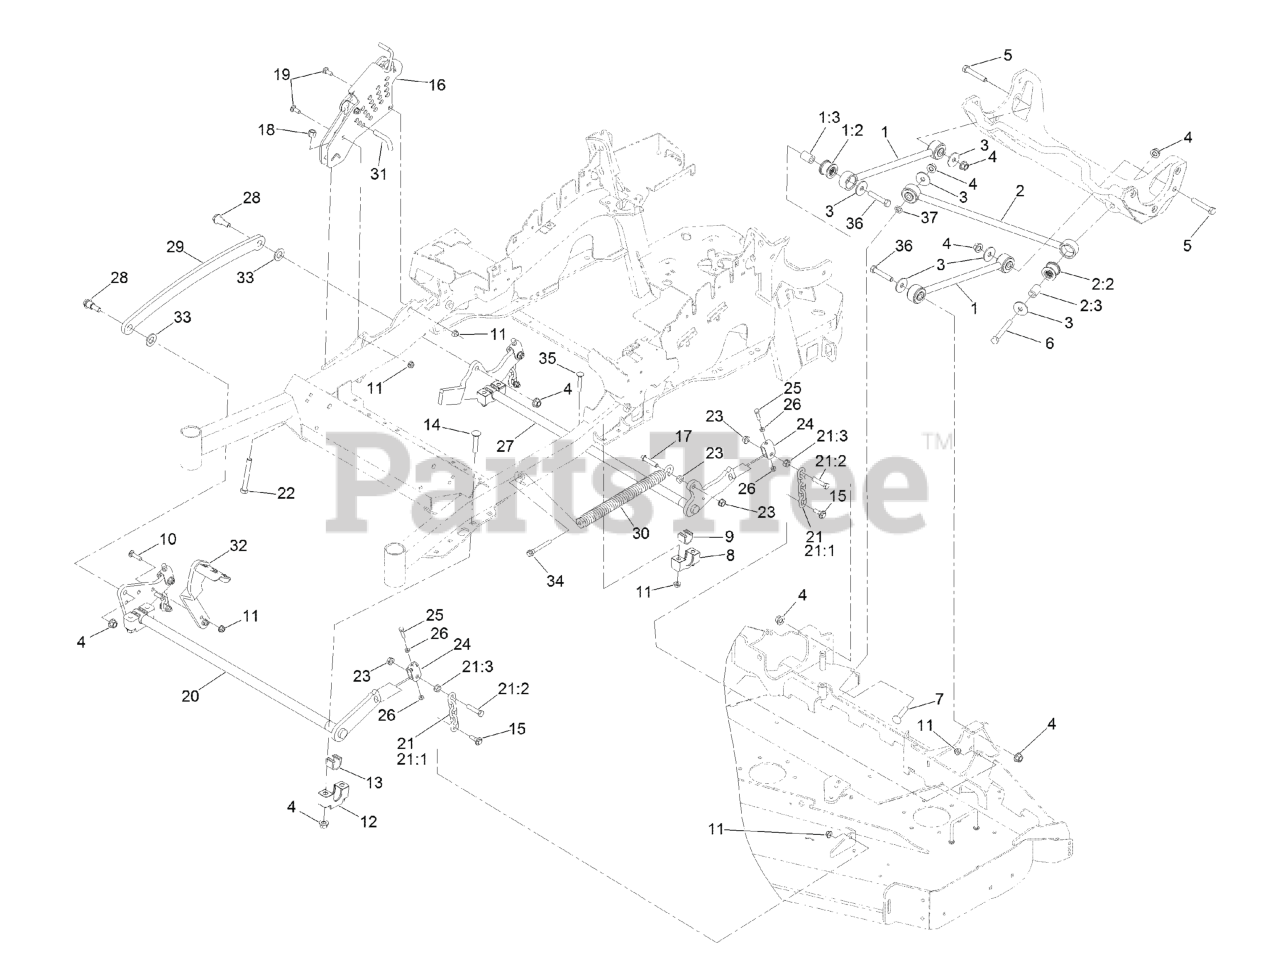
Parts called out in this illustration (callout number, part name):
1	DECK STRUT ASM
1:2	BUSHING-SUSPENSION, RUBBER
2	PANHARD ROD ASM
2:2	BUSHING-SUSPENSION, RUBBER
3	WASHER-THRUST
4	Nut-Lock 1/2-13
5	SCREW-HH
6	SCREW-HH
7	SCREW-CARR
8	SUPPORT-CROSS SHAFT, BEARING REAR
9	BEARING-CROSS SHAFT, REAR
10	SCREW-CARR
11	NUT-HF, NI
12	SUPPORT-CROSS SHAFT, BEARING
13	BEARING-CROSS SHAFT, FRON
14	Bolt-Carriage 1/2-13 X 2 1/2 Spl Neck
15	SCREW-SHOULDER, HHF
16	HOC ASM
17	SCREW-HH
18	NUT-LOCK, NI
19	BOLT-CARR
20	DECKLIFT-FRONT
21	DECK LIFT CHAIN ASM
21:1	CHAIN-LIFT, DECK
21:2	SCREW-HH
22	BOLT-TAP
24	YOKE-ADJUST, DECK
25	SCREW-HH
26	NUT-JAM
27	LIFT-DECK, REAR
28	SCREW-SHOULDER, HHF 1/2-13 X 1.12
29	LINK-LIFT, DECK
30	SPRING-EXTENSION
31	PIN-HOC
32	LEVER-FOOT
33	WASHER-FLAT
34	BOLT-SHOULDER
35	Bolt-Carriage 3/8-16 X 2 1/4
36	SCREW-HH
37	NUT-PUSH
